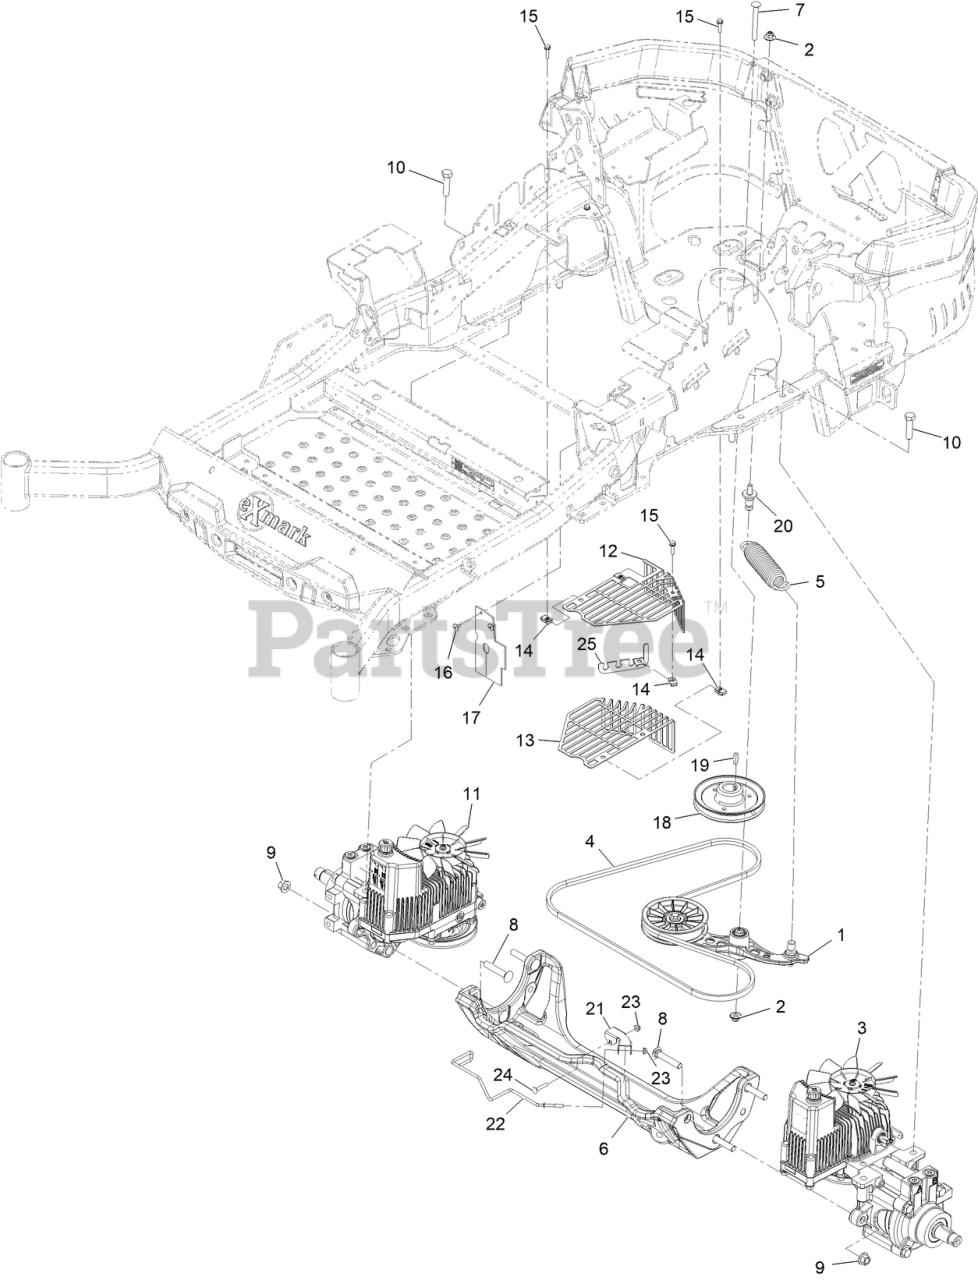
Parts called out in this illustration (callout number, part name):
1	PUMP IDLER ASM
2	Nut-Nyloc 3/8-16 Flg
3	HYDRO-LH
5	SPRING-EXTENSION
6	CRADLE-HYDRO
7	BOLT-SHOULDER, CARRIAGE 3/8-16 X 3 1/2
8	SCREW-CARR
9	Nut-Lock 1/2-13
10	SCREW-HH
11	HYDRO-RH
12	SHROUD-RH HYDRO
13	SHROUD-LH HYDRO
15	SCREW-HHF
16	RIVET-POP
17	DEFLECTOR-AIR FLOW
18	SHEAVE-W/ HUB 5.81
20	Pin-Spring, Anchor
21	Bracket-U
22	Guide-Belt
24	SCREW-CARR
25	Clip-Vent Lines
